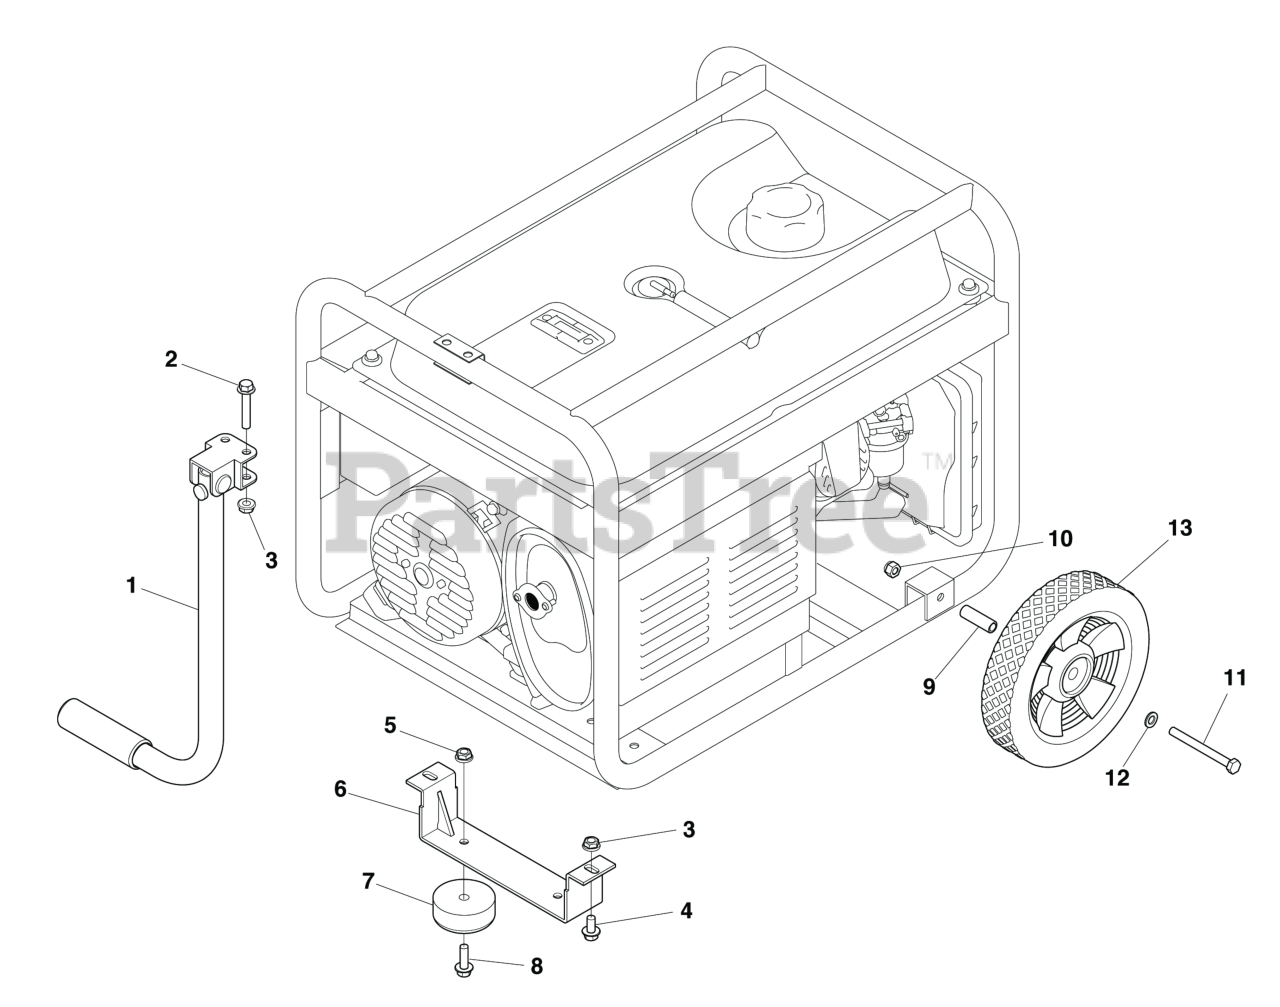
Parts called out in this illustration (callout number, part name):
3	NUT, M8 Flange
5	NUT, M6 Flange
10	NUT, M8 Locking
12	Washer, M8 Flat
